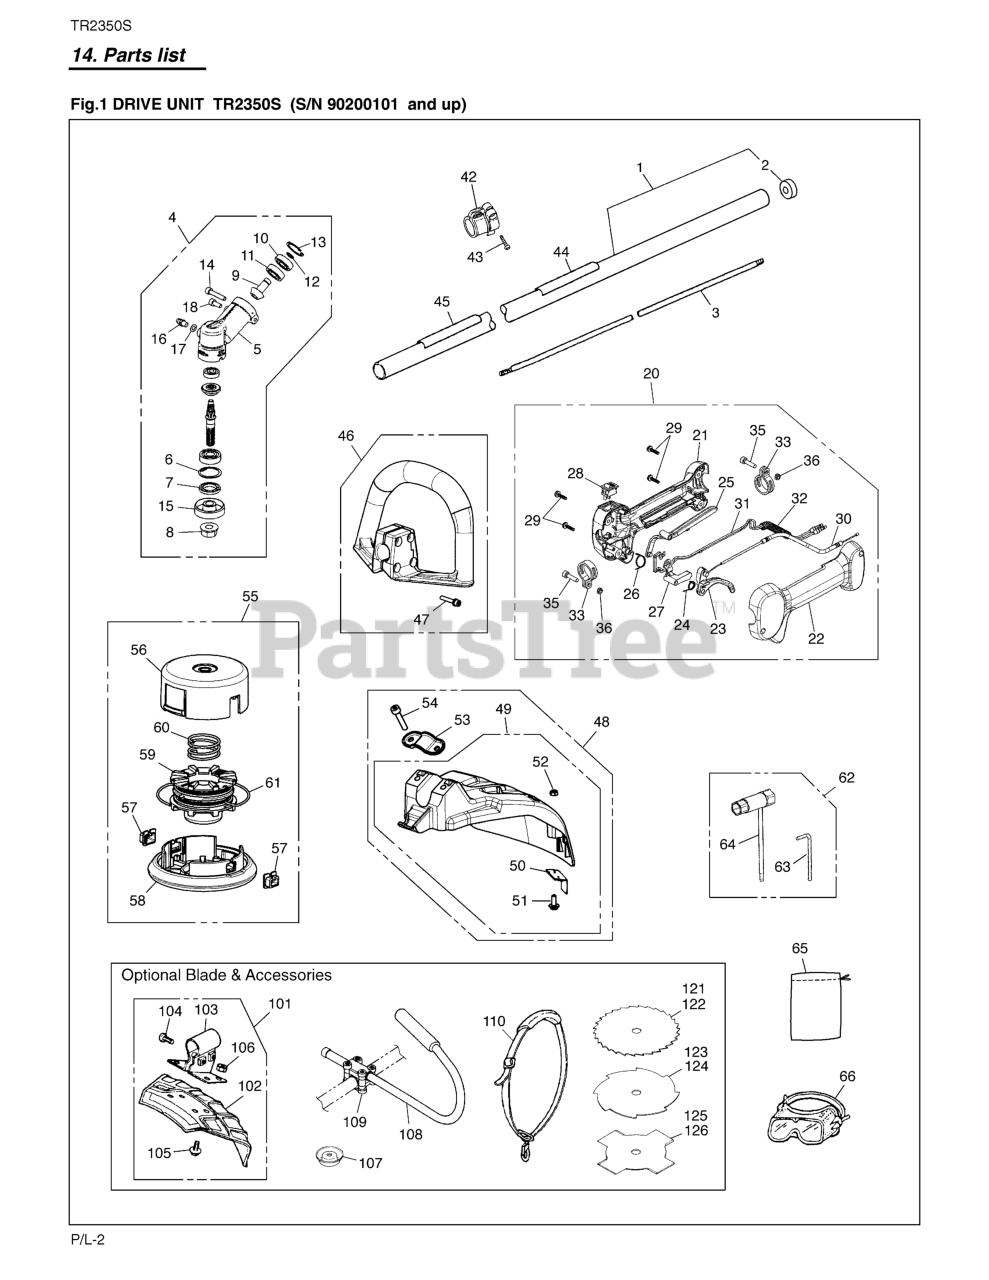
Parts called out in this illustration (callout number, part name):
1	PIPE COMP.
2	SEAL
3	SHAFT
4	GEARCASE ASSY.
5	GEARCASE
6	SNAP RING
7	SEAL
8	NUT
9	PINION
10	BEARING
11	BEARING
12	SNAP RING
13	RING, SNAP, M24 x 1.2
14	BOLT
15	HOLDER (A)
16	FITTING, GREASE
17	WASHER, FITTING
18	BOLT
20	GRIP ASSY
23	LEVER, THROTTLE
24	SPRING, THROTTLE
25	LEVER, SAFETY
27	LEVER, JOINT
28	SWITCH
29	SCREW
30	CABLE COMP
31	CORD COMP
32	TUBE
35	BOLT TORX
42	HANGER COMP.
43	SCREW
44	LABEL, NAME
45	LABEL, CAUTION
46	HANDLE ASSY
47	SCREW
48	GUARD ASSY.
49	GUARD ASSY.
50	BLADE
51	SCREW
52	NUT
53	CLAMP
54	BOLT
55	TAP HEAD COMP.
56	CASE
57	EYELET
58	COVER
59	CORD HOLDER
60	SPRING
62	TOOL SET
63	BAR
66	GOGGLE
101	GUARD ASSY.
102	GUARD
104	BOLT
105	SCREW
106	NUT M6
107	COVER
108	HANDLE, J
109	BRACKET
110	STRAP ASSY
121	BLADE, 9
122	BLADE, 9
123	BLADE, 8
124	BLADE, 9
125	BLADE, 8
126	BLADE, 9
